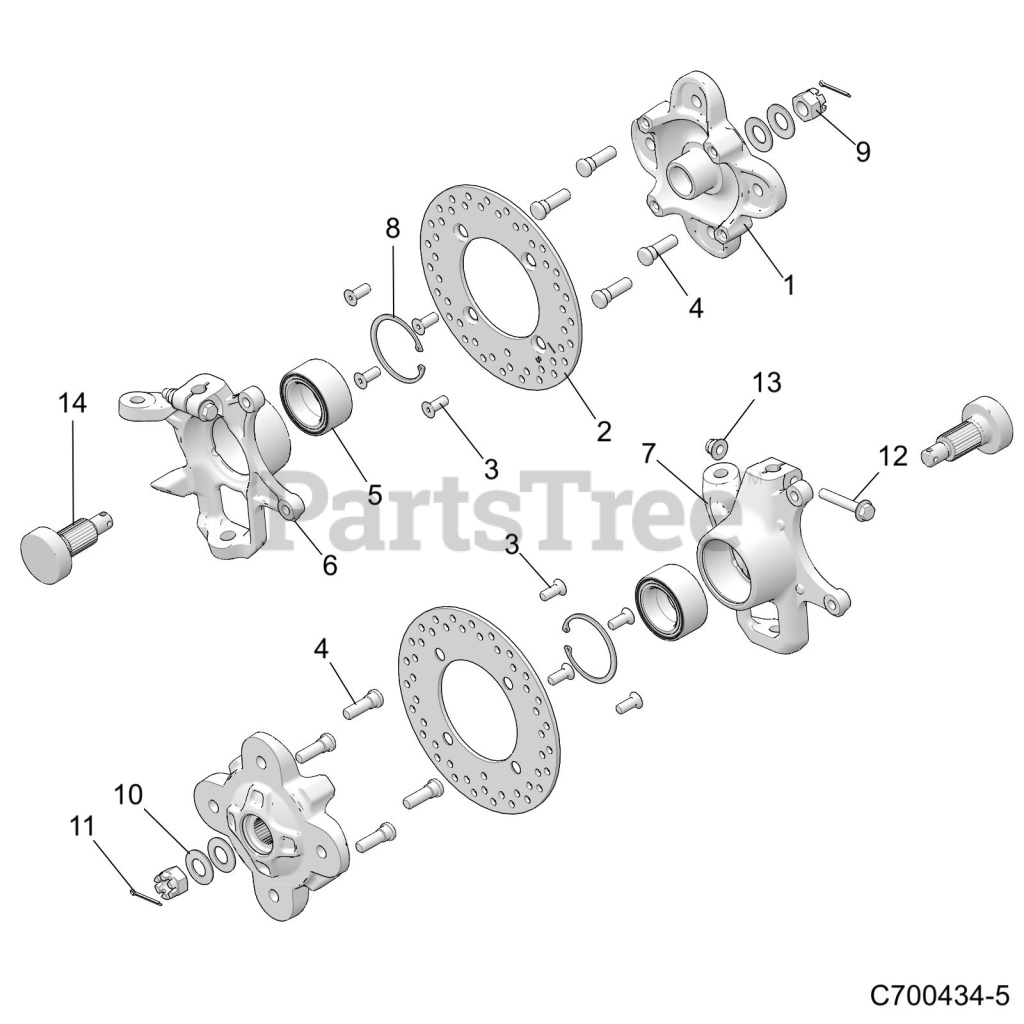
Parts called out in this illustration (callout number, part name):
1	HUB-WHEEL,FRONT MACH,BLK
2	ROTOR,BRAKE
3	SCR-M10X1.5X20 8.8 TXCS FL ZOD
4	STUD-WHEEL,M12-1.5
5	BEARING-BALL,SEALED,44X72X33.1
6	KNUCKLE-FRONT,LH
7	KNUCKLE-FRONT,RH
8	RING, RETAINING, INTERNAL
9	NUT-M18X1.5,CASTLE,ZINC/YELLOW
10	WASHER, CONE
11	PIN, COTTER
12	SCR-HXFL-M10X1.25X60 10.9 ZOD
13	NUT-M10X1.25,FLG,NYLOC-OLIVE D
14	SPINDLE-FRONT
